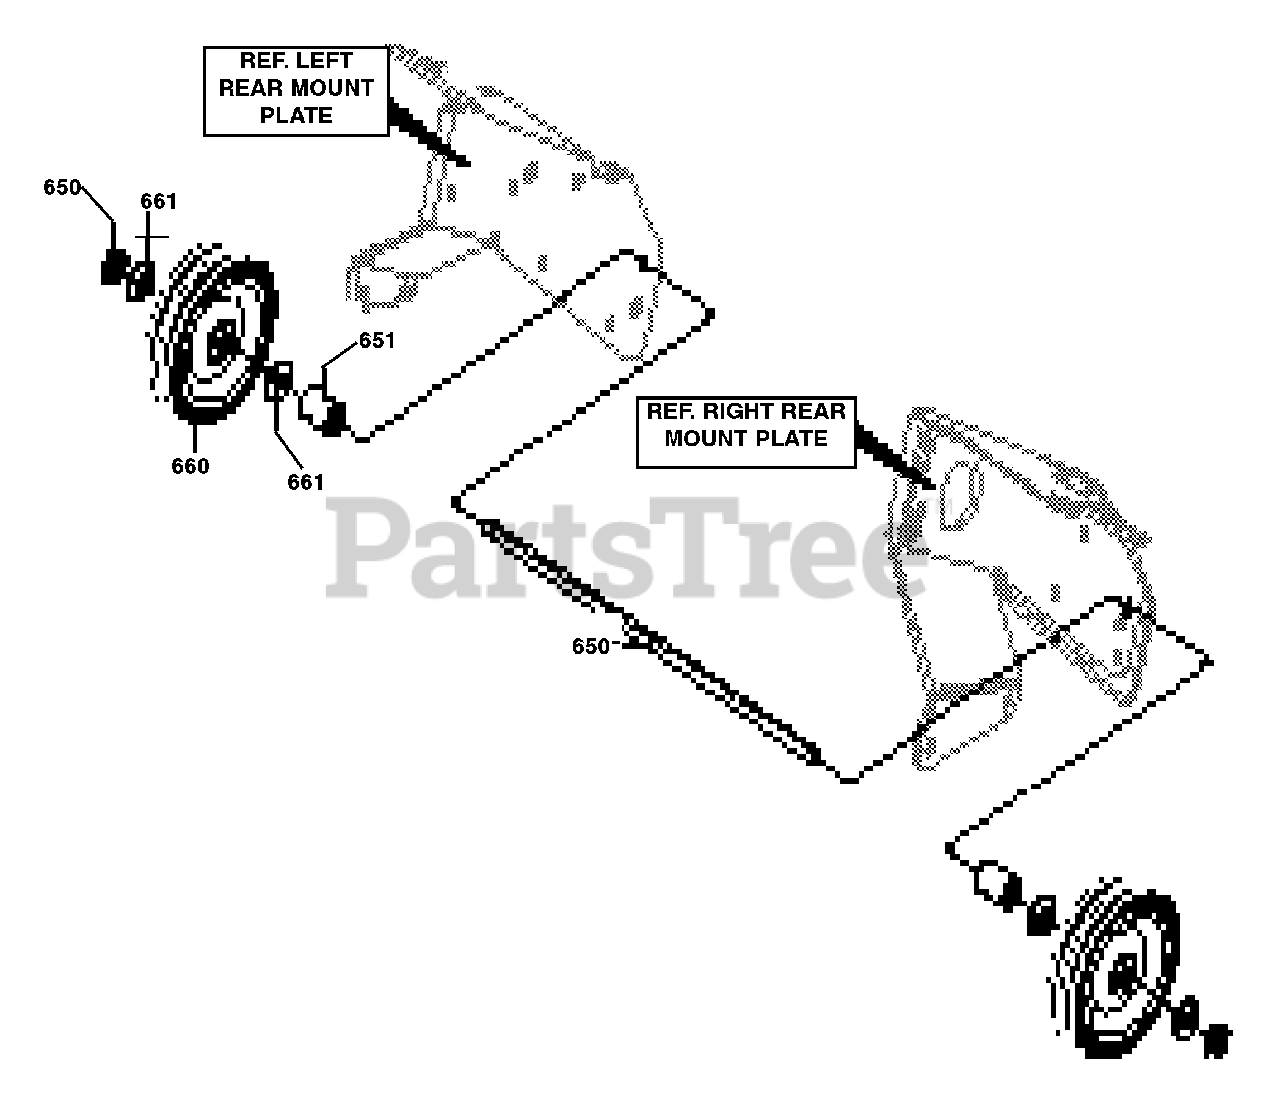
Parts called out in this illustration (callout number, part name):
650	SHAFT, AXLE
651	SPACER, SLEEVE
660	TIRE & RIM
661	WASHER, FLAT .406 X 81 X .065
662	RING, RET E
